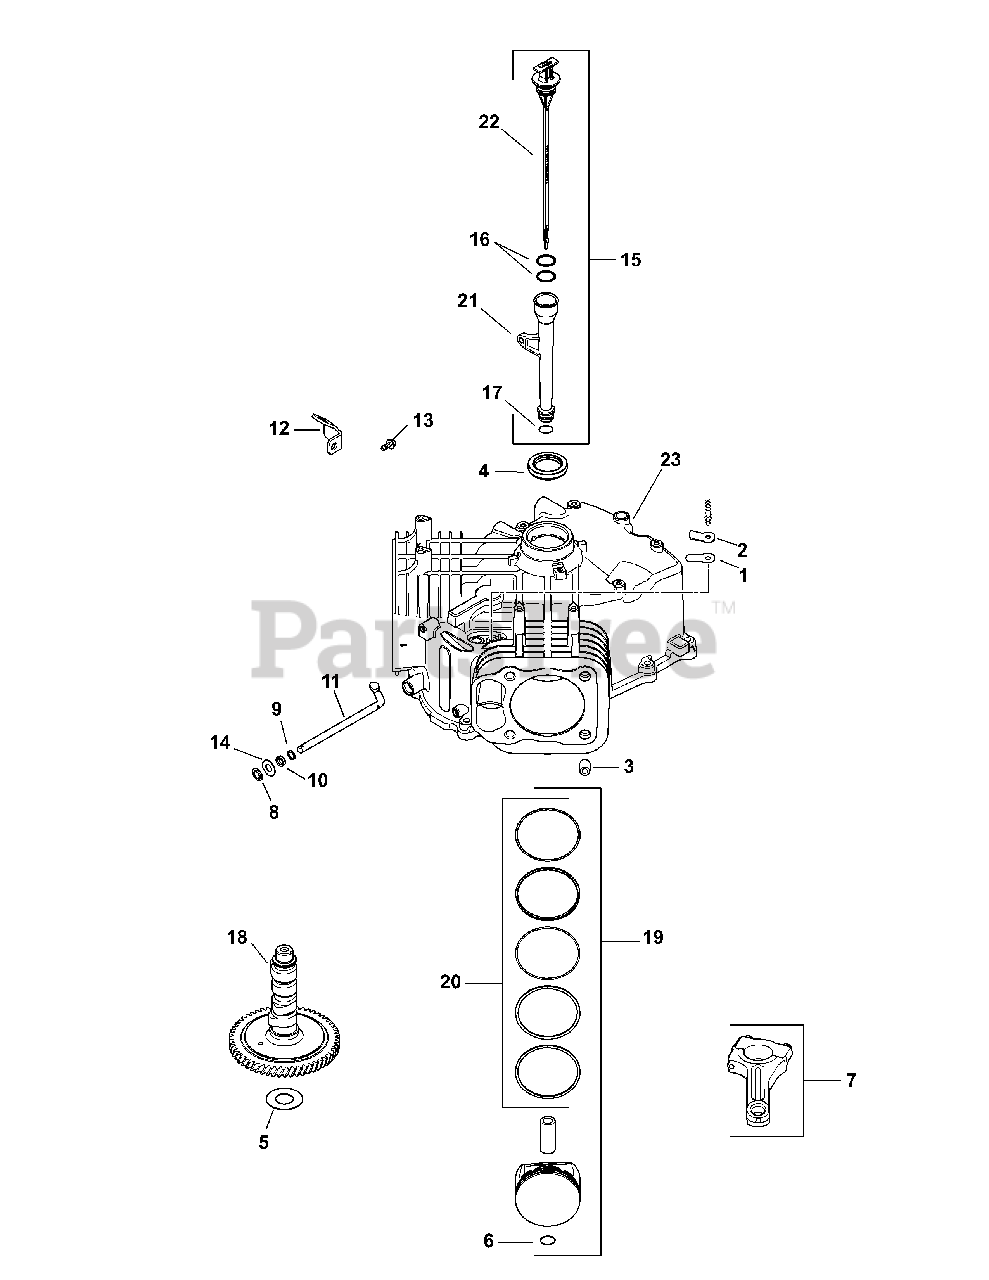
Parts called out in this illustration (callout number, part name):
1	Breather Reed
2	Breather Reed Retainer
4	Oil Seal, 1.78 x 1.26
5	Camshaft Shim (White, .028)
5	Camshaft Shim (Blue, .03)
5	Camshaft Shim (Red, .032)
5	Camshaft Shim (Yellow, .034)
5	Camshaft Shim (Green, .036)
5	Camshaft Shim (Gray, .038)
5	Camshaft Shim (Black, .04)
6	Piston Pin Retainer
7	Connecting Rod (STD)
8	Ring Retainer
9	Flat Washer, 11/32
10	Governor Cross Shaft Seal
11	Governor Cross Shaft
12	Oil Fill Tube Bracket
13	Flange Screw, M5 x .8 x 13
14	Flat Washer, 9mm
15	Dipstick & Tube Kit
17	Lower Oil Fill Tube O-Ring
18	Camshaft Assembly
19	Piston Kit w/ Ring
19	Piston Kit w/ Ring (0.25) 83mm
19	Piston Kit w/ Ring (0.08) 83mm
20	Ring Set, Piston STD
20	Ring Set, Piston (.08)
20	Ring Set, Piston (.25)
21	Tube Assembly
22	Dipstick Assembly
23	Crankcase
